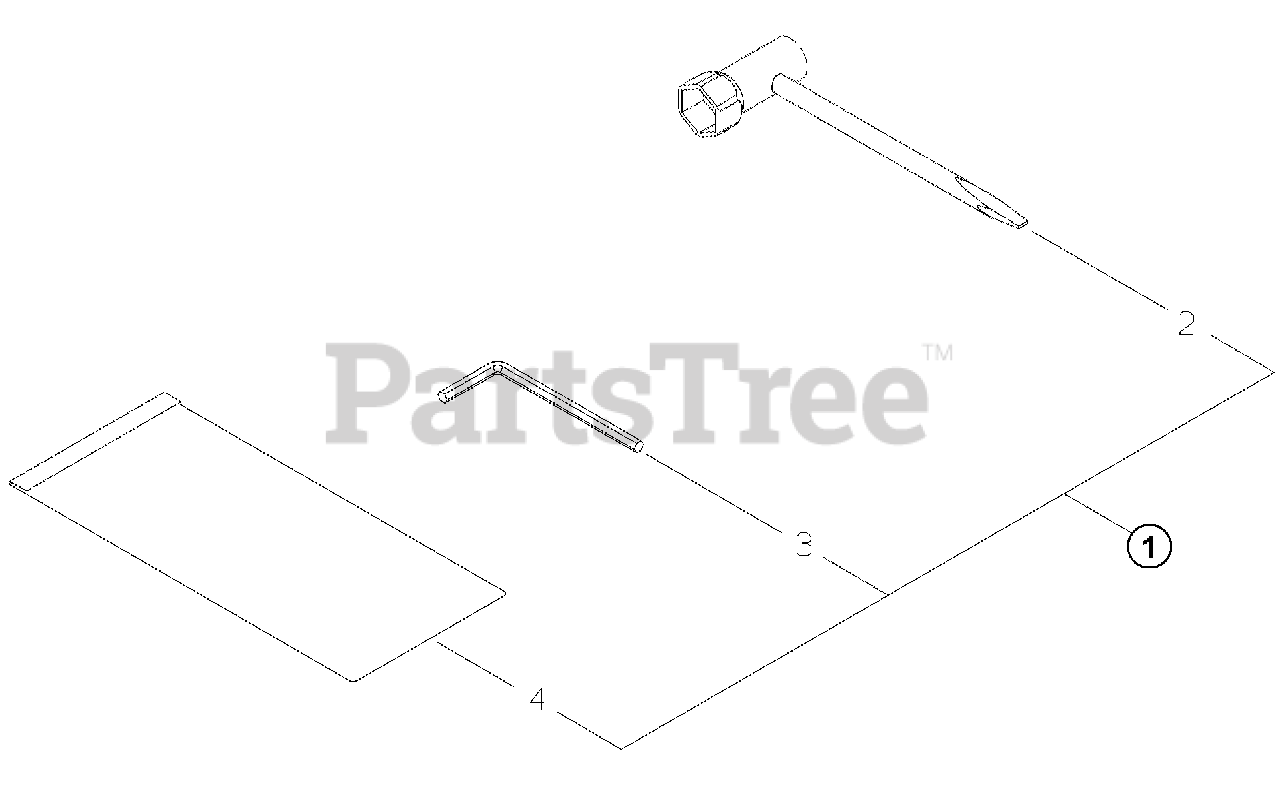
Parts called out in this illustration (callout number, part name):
1	TOOL KIT, SERVICE
2	T-WRENCH 16×13
3	WRENCH, ALLEN 4 MM
4	BAG, TOOL
